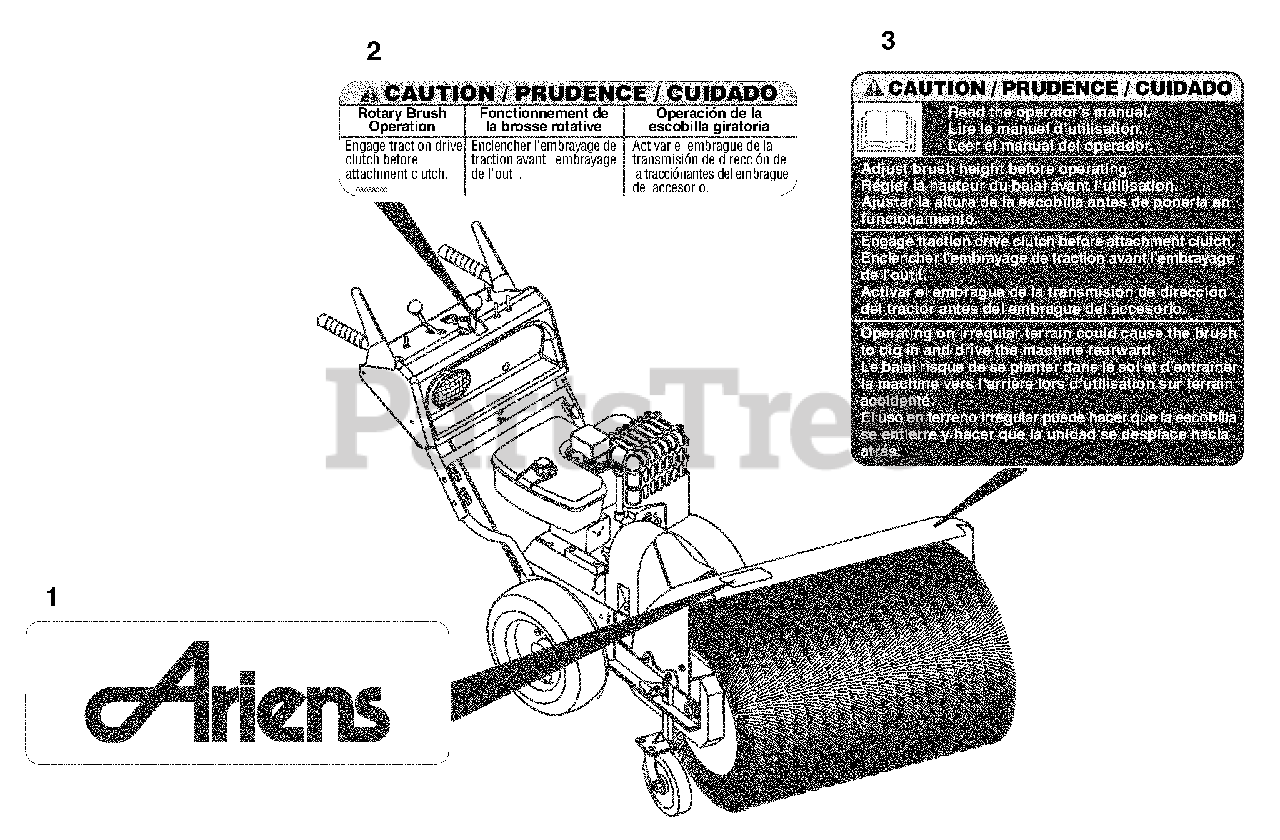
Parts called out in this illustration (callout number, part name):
1	DECAL - ARIENS
2	DECAL, CAUTION - BRUSH
3	DECAL, DANGER - POWER BRUSH
